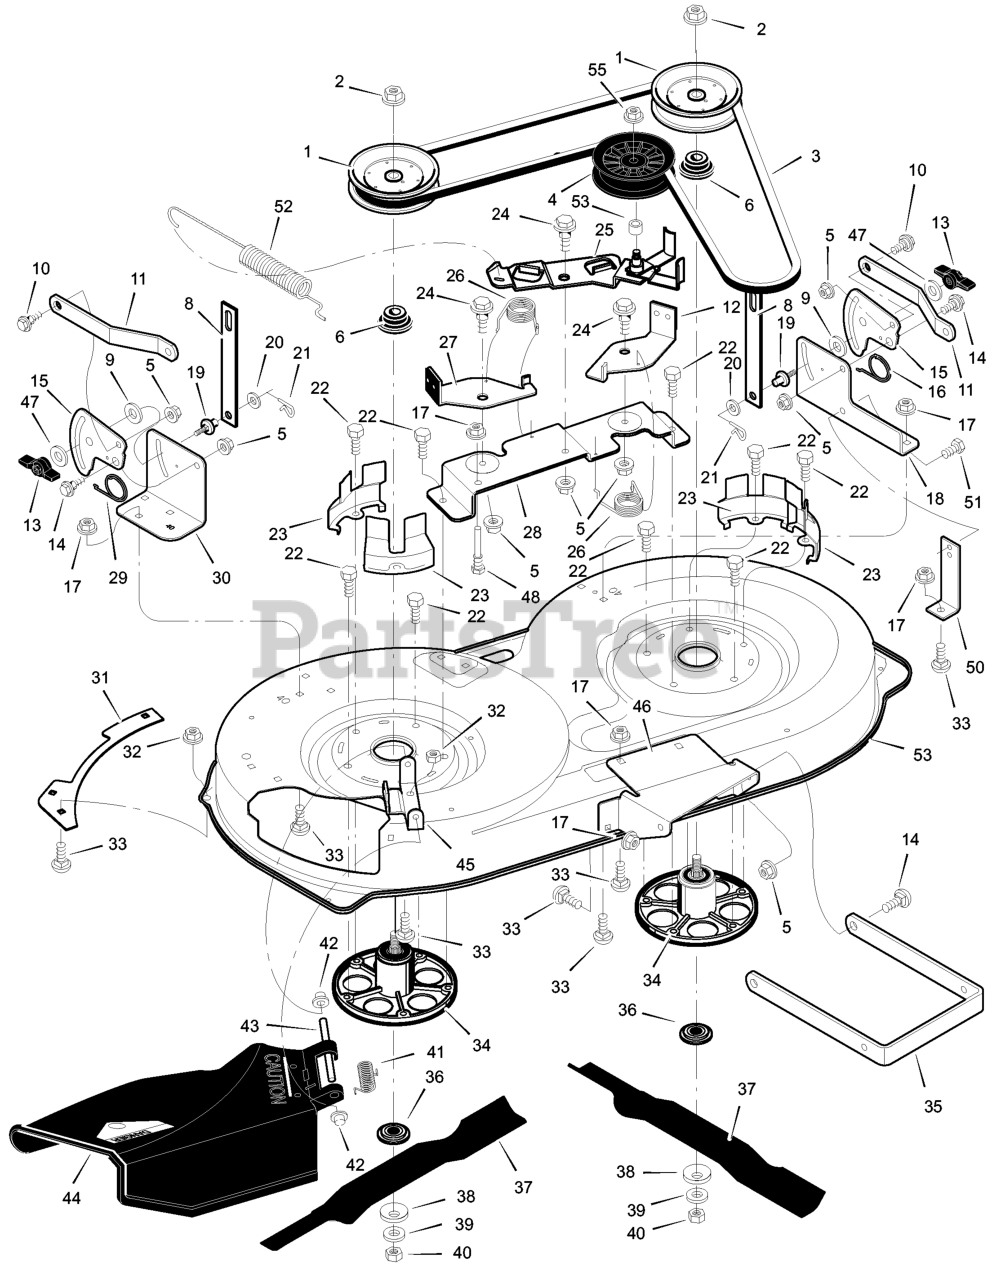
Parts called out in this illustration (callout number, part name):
1	Pulley, Jackshaft
2	Nut, Hex
3	Belt, Mower Drive
4	Pulley, Idler
5	Nut, Flange
6	Spacer, Pulley
8	Link, Lift
9	Pad, Friction
10	Bolt, Shoulder
11	Bracket, Suspension
12	Pad Assembly, Left Brake
13	Knob
14	Bolt, Shoulder
15	Plate, Suspension
17	Nut, Flange
18	Bracket, Suspension
19	Pin, Hanger
21	Pin, Cotter
22	Bolt
23	Cover, Pulley
24	Bolt, Shoulder
25	Arm, Idler
27	Pad Assembly, Right Brake
28	Bracket Assembly, Brake
30	Bracket, Suspension
31	Plate
32	Nut, Flange
33	Bolt, Carriage
34	Mandrell
35	Bracket, Suspension
36	Adapter, Blade
42	Cap, Push On
43	ROD, Deflector
44	Deflector Assembly
45	Bracket, Deflector
46	Bracket, Front Hanger
48	Guide, Belt
50	Bracket, Support
52	Spring, Extension
54	Housing, Blade
55	Nut, Flange
